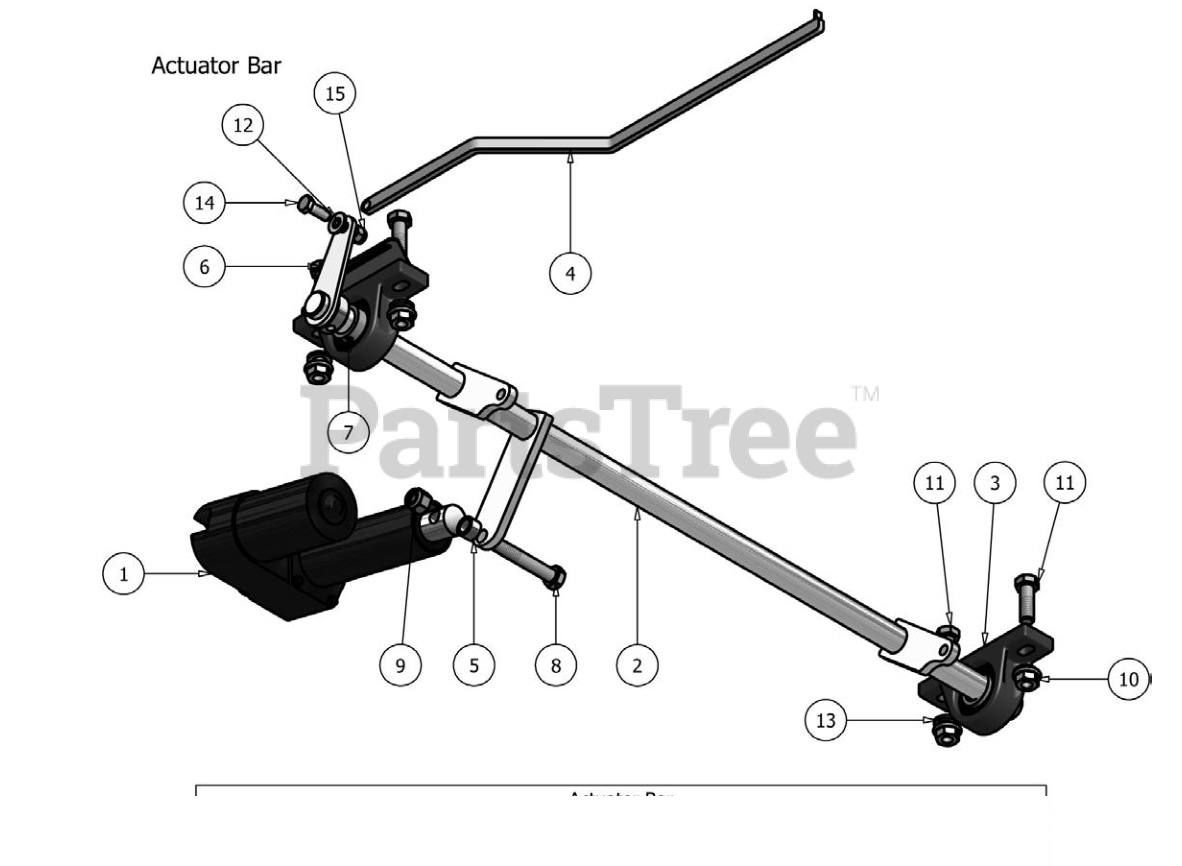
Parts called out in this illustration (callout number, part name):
2	Actuator Bar
3	1" Pillow Block
4	Height Indicator
5	1/2" x 1/2" Collar Spacer
6	2006 Height Indicator Lever
7	3/8" Set Screw
8	1/2" x 3" Hex Bolt
9	1/2" Nylock Nut
10	1/2" Flange Nut
11	1/2" x 1 1/2" Hex Bolt
12	.360 ID Plastic Washer
13	1/2" Lock Washer
14	3/8" x 1" Hex Bolt
15	3/8 Nylock Nut
